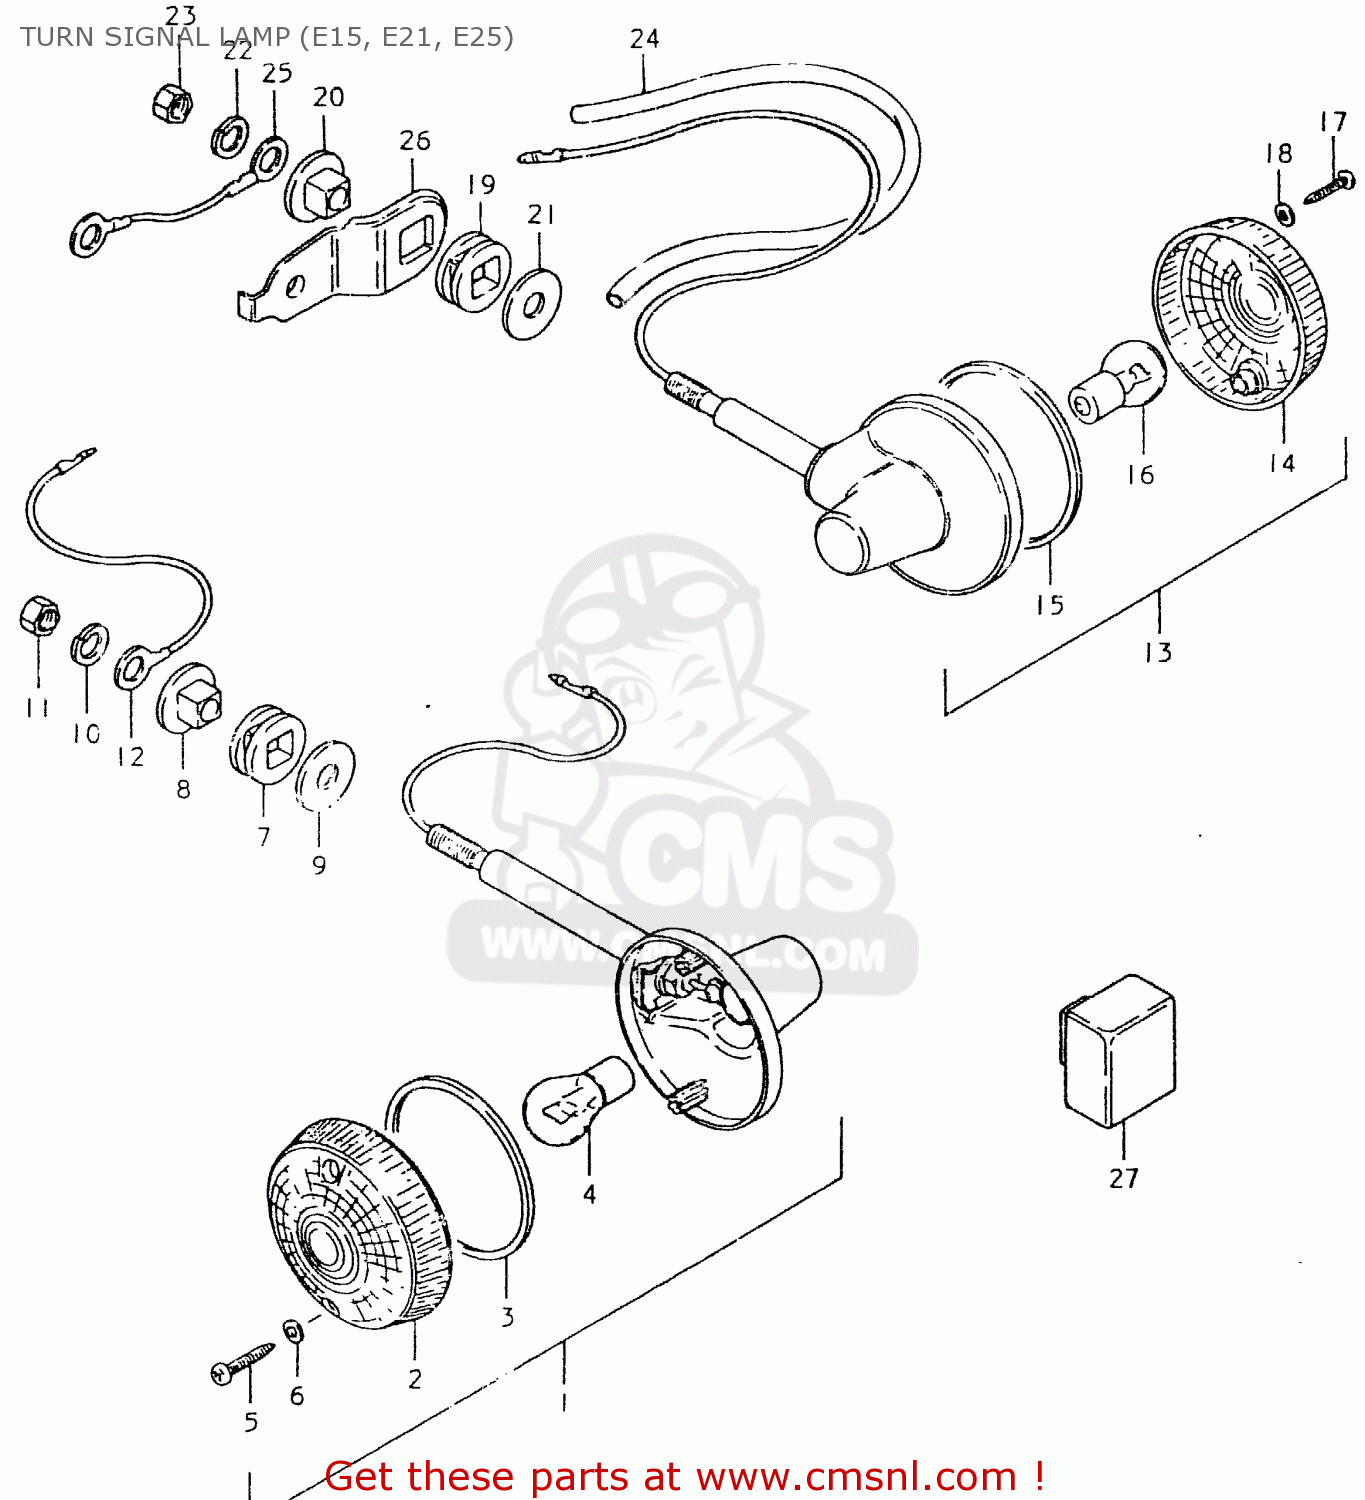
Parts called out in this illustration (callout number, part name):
1	LAMP ASSY, FRONT TURN SIGNAL
2	LENS
3	GASKET (NAS)
4	BULB (6V,21W)
5	SCREW
6	GASKET (NAS)
7	CUSHION
8	SPACER,TURN SIGNAL LAMP
9	WASHER (10.5X30X2.3)
10	LOCK WASHER
11	NUT
12	LEAD WIRE,EARTH
13	LAMP ASSY, REAR TURN SIGNAL
14	LENS
15	GASKET (NAS)
16	BULB (6V,21W)
17	SCREW
18	GASKET (NAS)
19	CUSHION
20	SPACER,TURN SIGNAL LAMP
21	WASHER (10.5X30X2.3)
22	LOCK WASHER
23	NUT
24	PROTECTOR, LEAD WIRE
25	LEAD WIRE,EARTH
26	BRACKET,REAR TURN SIGNAL
27	RELAY, TURN SIGNAL
